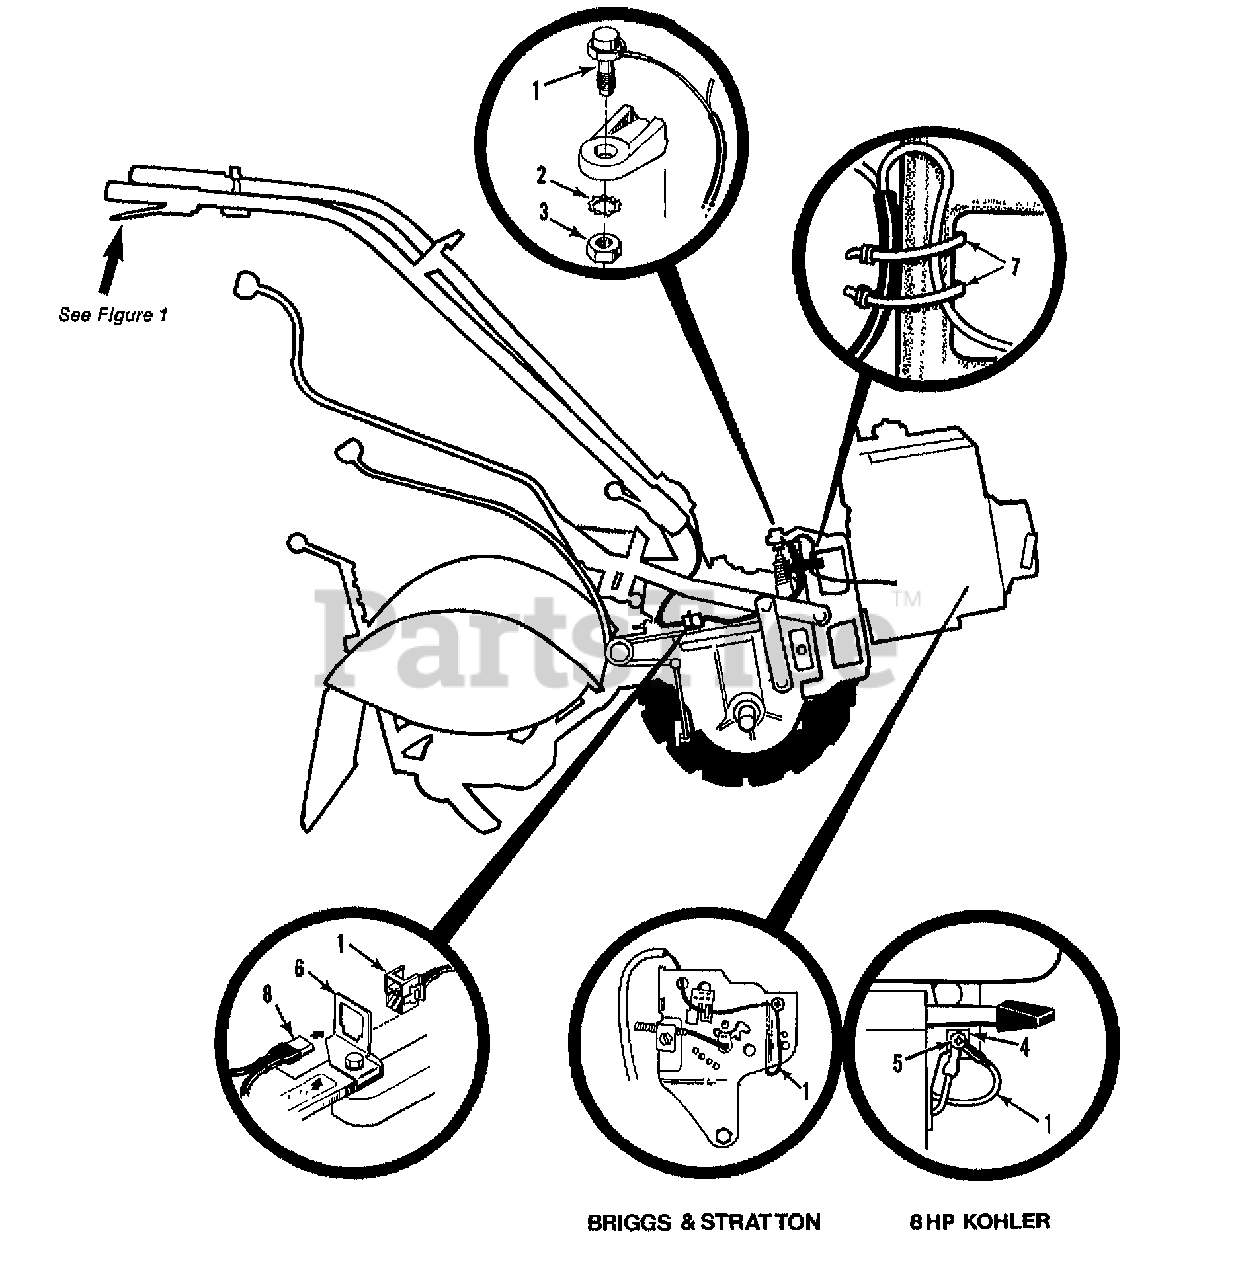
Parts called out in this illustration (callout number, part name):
1	HARNESS-WIRE ENG OPC
2	WASHER-LK .438 EXT TOOTH
3	NUT-HEX/JAM 7/16-20
4	GROMMET-7 T/L & 8 KOH OPC
5	SCR #8-18 SELF TAP
6	CLIP-CONNECTOR
7	TIE-RED
8	HARNESS-WIRE OPC HORSE
